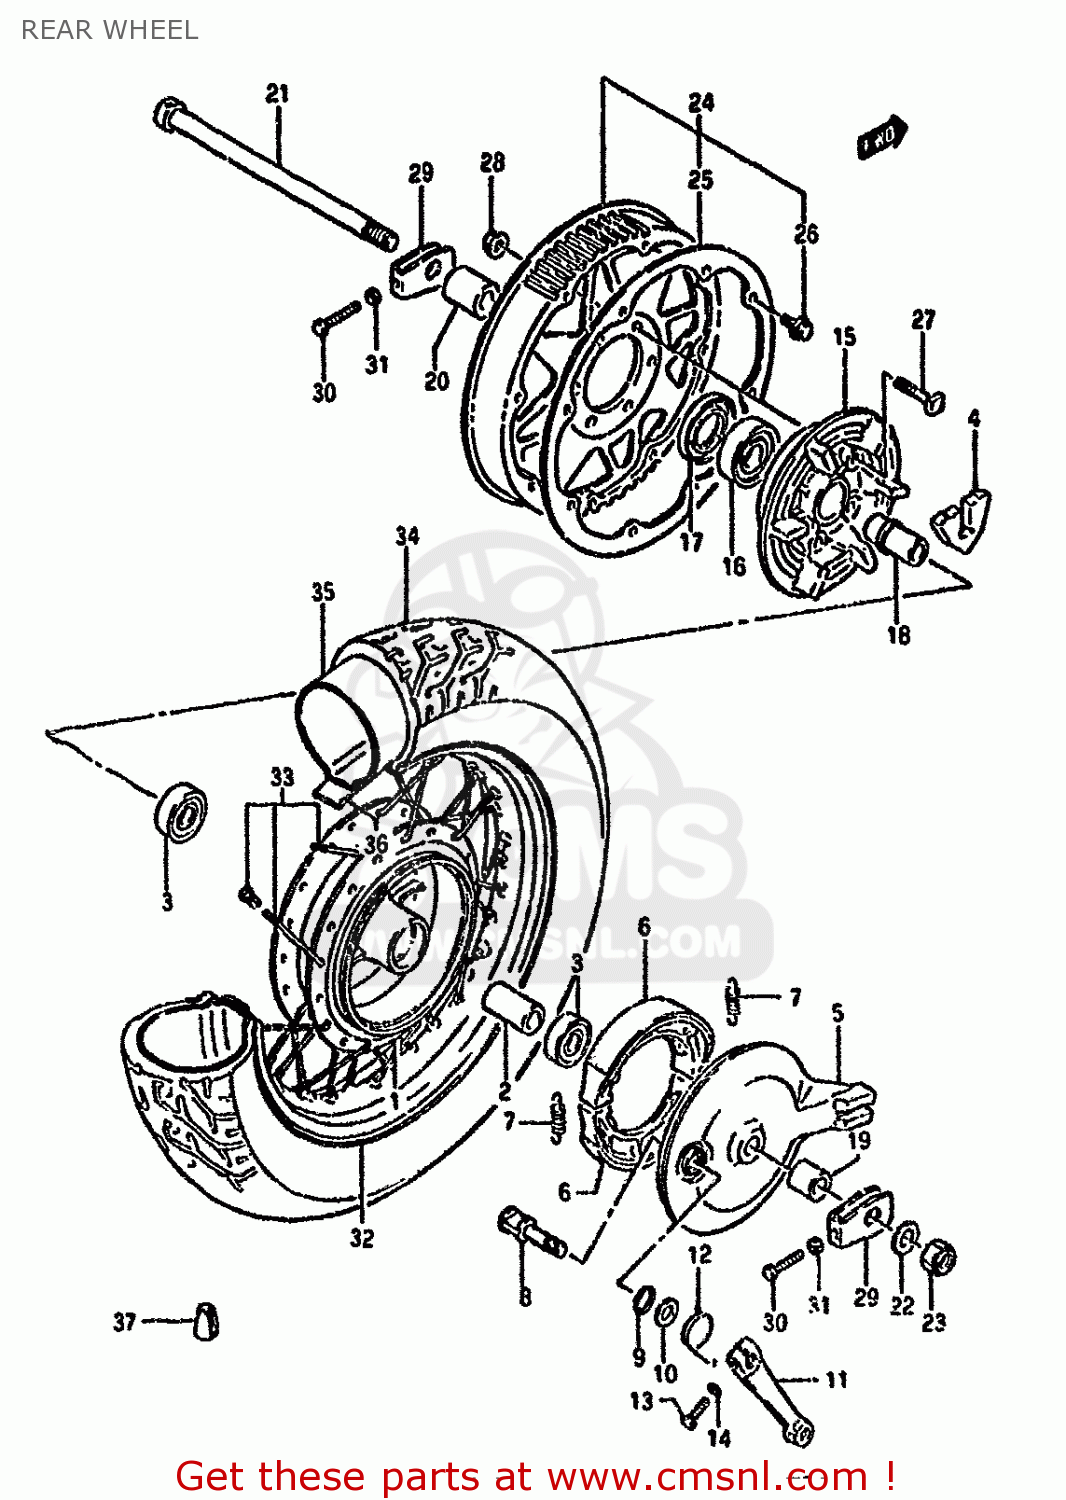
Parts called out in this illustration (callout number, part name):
1	HUB,RR WHEEL
2	SPACER(17.5X25X70)
3	BEARING
4	ABSORBER,RR HUB SHOCK
5	PANEL,REAR HUB
6	SHOE,BRAKE
7	SPRING,BRAKE SHOE
8	CAM,BRAKE
9	O-RING,BOSS
10	WASHER (15X24X1.6)
11	LEVER,RR BRAKE CAM
12	SPRING
13	BOLT
14	WASHER,LOCK
15	DRUM,RR SPROCKET MOUNTING
16	BEARING(25X62X17)
17	SEAL,OIL(33X62X7)
18	RETAINER,RR SPROCKET DRUM
19	SPACER(17X28X22.3)
20	SPACER(17X33X35.3)
21	AXLE,REAR
22	WASHER (17X30X3.2)
23	NUT
24	SPROCKET,REAR
25	PLATE,REAR SPROCKET
26	BOLT
27	BOLT(10X40)
28	NUT 10MM
29	ADJUSTER,BELT
30	BOLT 8X35
31	NUT
32	RIM,REAR WHEEL
33	SPOKE SET,RR WHEEL
34	TIRE
35	TUBE ASSEMBLY,WHEEL,INNER
36	PROTECTOR
37	BALANCER,WHEEL
